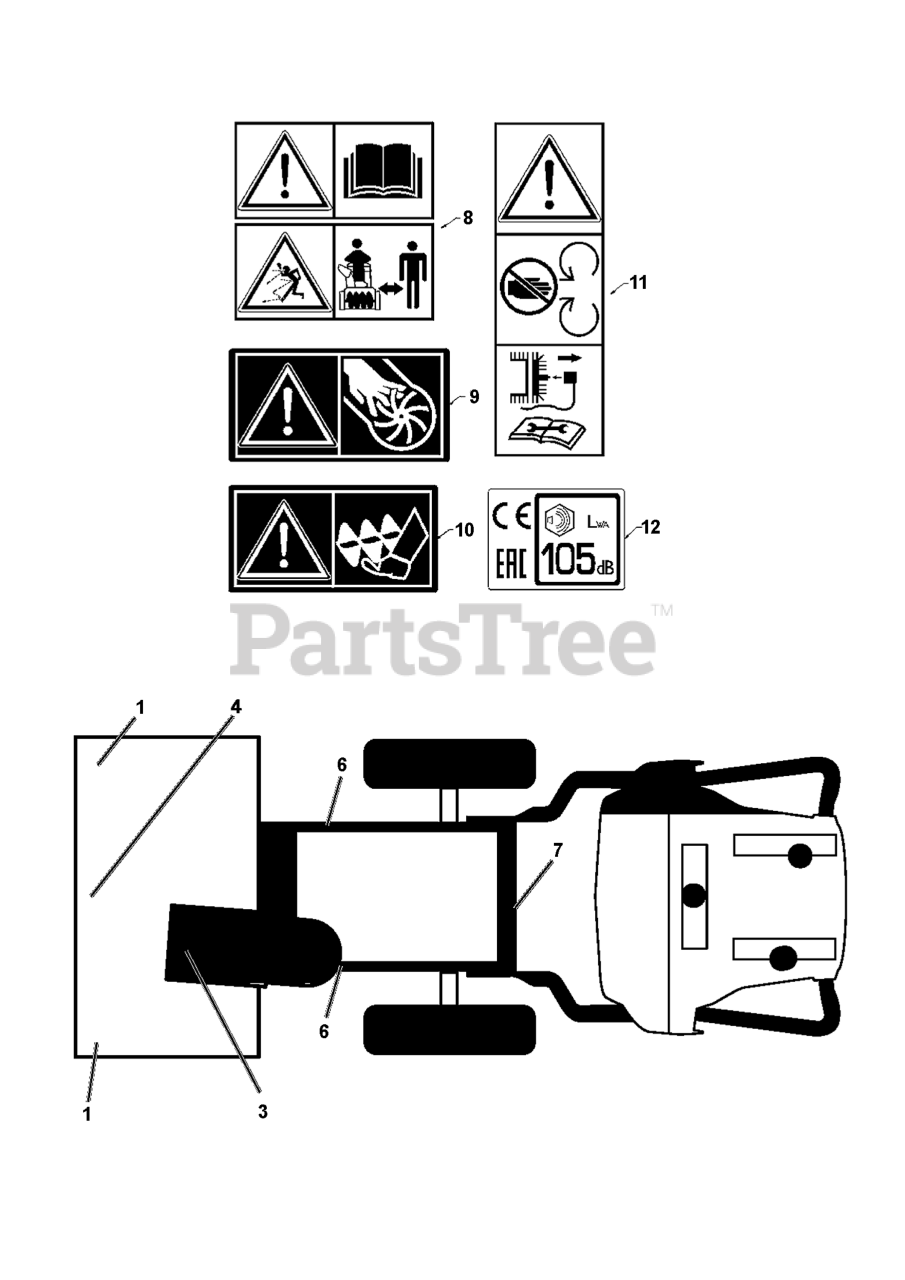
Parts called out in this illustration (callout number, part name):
1	DECAL.AUGER.SAFETY.
3	DECAL.CHUTE.SAFETY.EU/SC.17
4	DECAL.AUGER."
6	DECAL.BELT.GUARD.
6	DECAL.NOISE.LEV.105/CE.EAC.UKR
7	DECAL.NOISE.LEV.105/CE.EAC.UKR
8	DECAL.AUGER."
9	DECAL.AUGER.SAFETY.
10	DECAL.CHUTE.SAFETY.EU/SC.17
11	DECAL.BELT.GUARD.
12	DECAL.NOISE.LEV.105/CE.EAC.UKR
